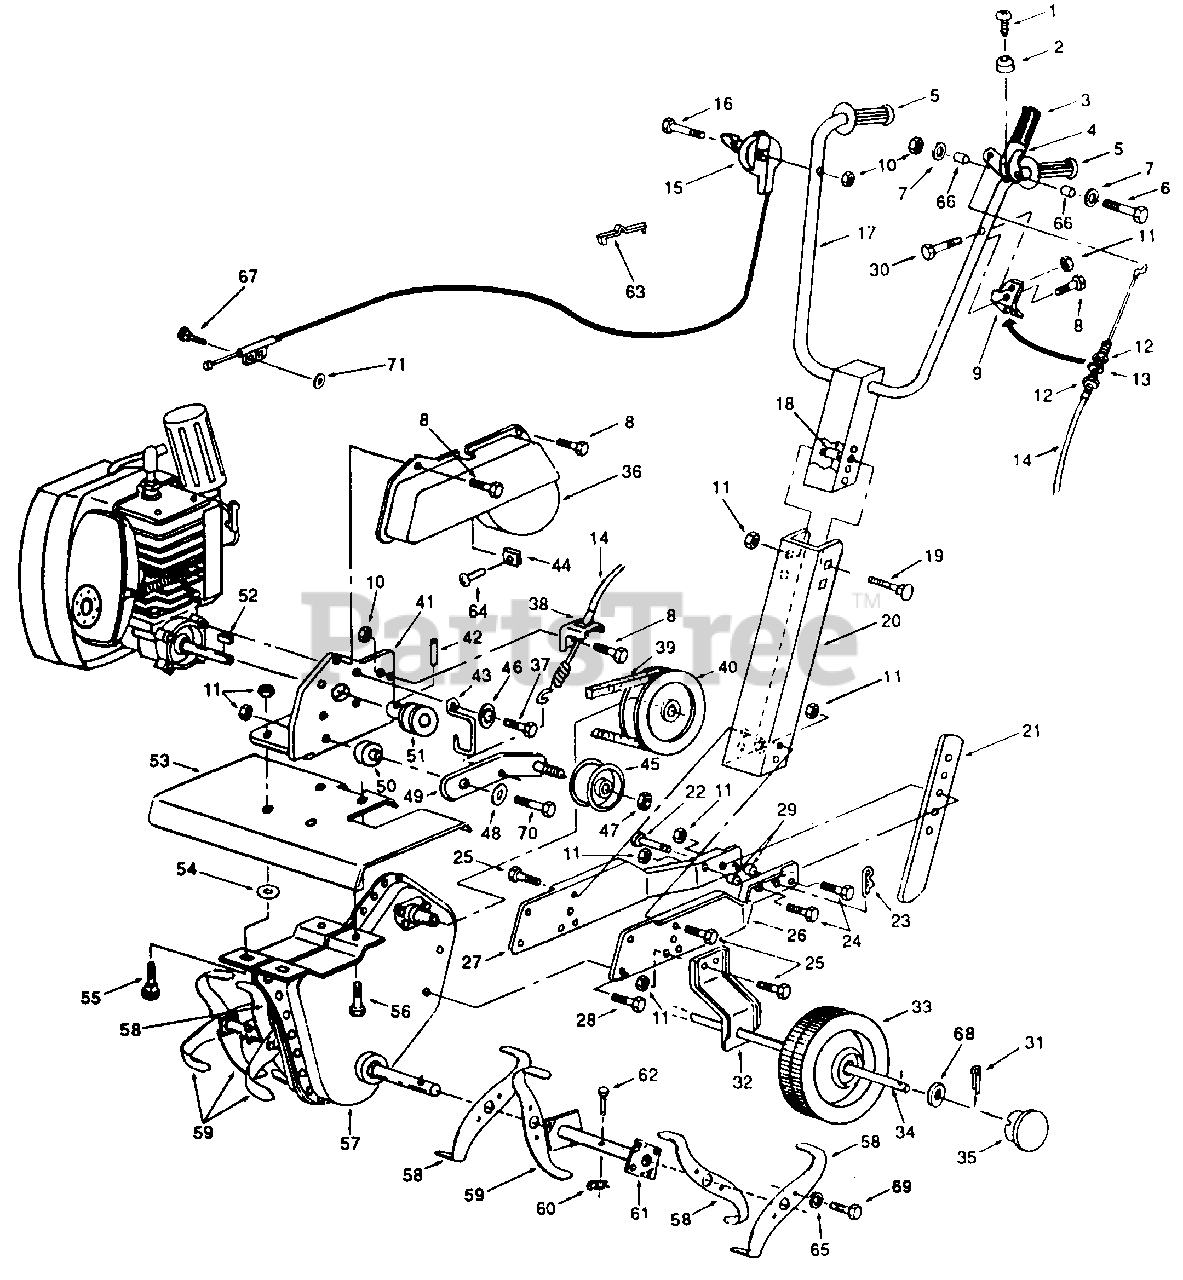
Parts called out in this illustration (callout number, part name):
1	Tap Scr. #10-16 x 1/2
2	Rubber Bumper
5	Handle Grip
6	Hex Boit 1/4-20 x 2"*
7	Fl-Wash. 1/4" I.D.
8	Hex Tap Scr. 1/4-20 x 1/2
9	Cable Bracket
10	Lock Nut 1/4-20 Thd.
11	Lock Nut 5/16-18 Thd.
12	Hex Jam Nut 5/16-24 Thd.
13	L-Wash. 5/16" I.D.*
14	Clutch Control Cable
15	Throttle Control
16	Hex Bolt 1/4-20 x 1-1/2"*
19	Carr. Bolt 5/16-18 x 2-1/2"
23	Hairpin Cotter
24	Hex Bolt 5/16-18 x 1"*
25	Hex Bolt 5/16-18 x 518"*
29	Spacer
30	Hex Bolt 5/16-18 x 1-1/4"
31	Cotter Pin
36	Belt Cover
37	Hex Bolt 1/4-20 x 5/8"*
38	Bracket-Clutch Lever
39	V-Belt
40	Pulley-Chain Case
41	Plate-Engine Mounting
42	Set Screw 5/16-18 x 3/8"
43	Belt Retainer
44	Clip-Tinnerman
45	Flat Idler Pulley
46	Int. L-Wash. 114" I.D.
47	Hex Jam Thd. L-Nut 318-24
48	Fl-Wash. 5116" I.D.
49	Idler Arm Ass'y.
50	Pivot Spacer
51	Engine Pulley
52	Square Key 1/8 x 3/4"
53	Tine Shield
55	Carriage Bolt 5/16-18 x 1"
56	Hex Bolt 5/16-18 x 3/4"*
57	Chain Case Ass'y. Comp.
58	R.H. Tine Blade
59	L.H. Tine Blade
60	Hairpin Cotter
61	Adapter Ass'y.-Tine
63	Cable Tie-Plastic
64	Scr. #10-16 x 3/4 Sems
65	L-Wash. 1/4" I.D.
67	Screw
68	Fl-Wash. 3/8" I.D.
69	Tap Scr. 1/4-20 x 1- 1/2"
70	Hex Bolt 5/16-18 x 1-1/2"
